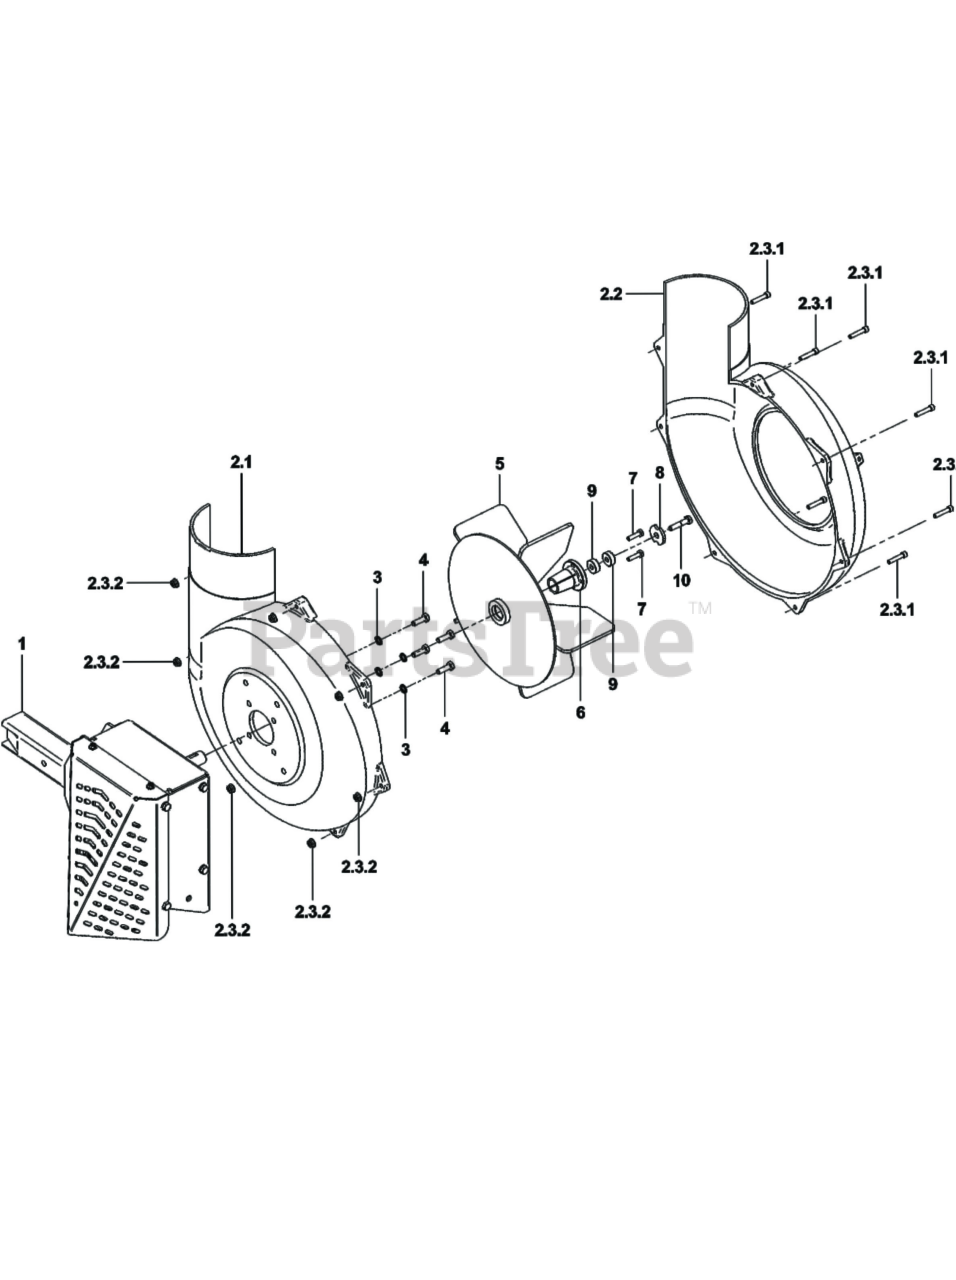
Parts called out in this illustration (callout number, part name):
1	DRIVE ASSEMBLY BASE
2	BLOWER HOUSING ASSEMBLY
2.1	BLOWER HSG BACK
2.2	BLOWER HSG FRONT
2.3	HARDWARE BAG-E5007A HOUSING
2.3.1	1/4-20x1-1/4 SHCS/zinc/GR8
2.3.2	NUT-FLANGE 1/4-20
3	I/T TOOTH LOCK WASHER
4	HEX SCREW HEAD 5/1
5	5 BLADE IMPELLER
6	TAPER LOCK BUSHING 7/8"
7	BOLT-HEX 1/4-20 X
8	DBL INDENTED WASHER 3/8"
9	SPACER BUSHING
10	SCREW 5/16"-24 X 1.5" GR8
